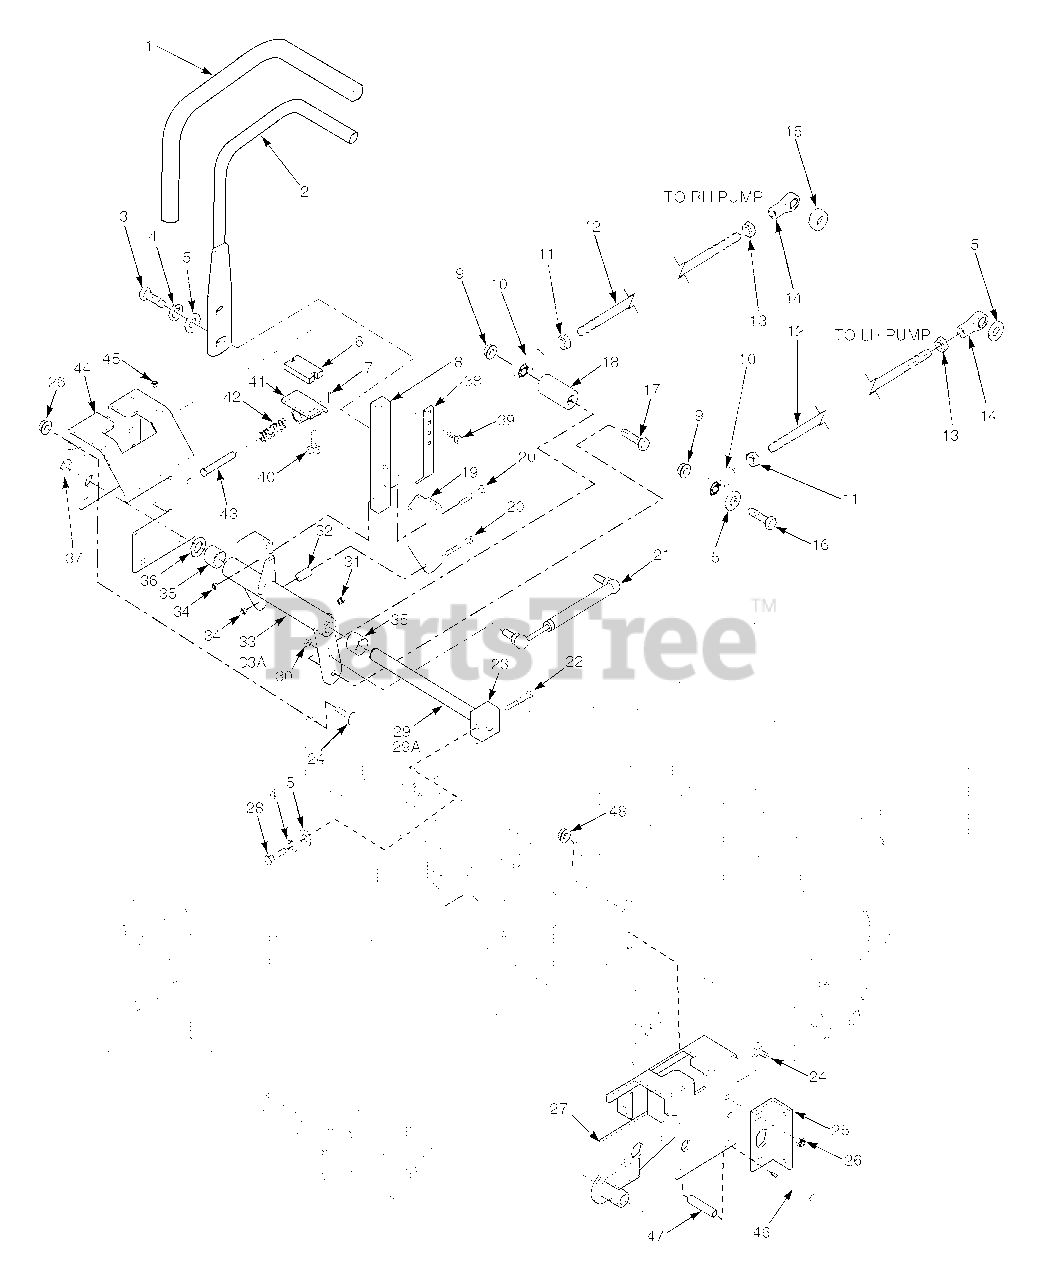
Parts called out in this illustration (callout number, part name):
1	Grip, Control Lever
2	Handle Bar
3	Bolt, Hex Head 3/8-16 x 1-1/4"
4	Lock Washer, 3/8"
5	Flatwasher, 3/8-.391 x .938 x .105
6	Spacer
7	Roll Pin, Spring 5/32 x 3/4"
8	Bar, Control Lever
9	Nut, Elastic Stop 3/8-16
10	Rod End, 3/8-24 RH Female
11	Nut, 3/8-24 RK Thread
12	Rod, Pump Control Linkage
13	Nut, 3/8-24 UNF-2B LH Thread
14	Rod End, 3/8-24 LH Thread
15	Spacer
16	Bolt, Hex Head 3/8-16 x 1-1/2"
17	Bolt, Hex Head 3/8-16 x 3-1/4"
18	Spacer
19	Plate, Control Lever
20	Bolt, Hex Head 5/16-18 x 2"
21	Gas Damper
22	Bolt, Hex Head 3/8-16 x 1-3/4"
23	Block Clamping
24	Bolt, Carr. 5/16-18 x 3/4"
25	Bracket, Fuel Tank Front
26	Nut, Serr. Flange 5/16-18
27	Control Plate Weldment LH w/decal
28	Bolt, Hex Head 3/8-16 x 3/4"
29	Shaft, Steering Control LH
29A	Shaft, Steering Control RH
30	Lock Nut 5/16-18
31	Grease Fitting, 1/4-28 Self Tap
32	Spacer, Control
33	Control Lever Weldment RH
33A	Control Lever Weldment LH
34	Nut, Elastic Stop 5/16-18
35	Bushing
36	Flatwasher, 1-1/4 x 49/64 x 16 Ga.
37	Retaining Ring, 3/4" Ext.
38	Bracket, Switch Actuator
39	Bolt, Hex Serr. Flange 5/16-18 x 3/4"
40	Bolt, Carr. 1/4-20 x 1"
41	Bracket, Control Return
42	Spring
43	Pin Retainer
44	Control Plate Weldment RH w/Decal
45	Nut, Elastic Stop 1/4-20
46	Bolt, Hex Head 3/8-16 x 6"
47	Spacer
48	Nut, Serr. Flange 3/8-16
